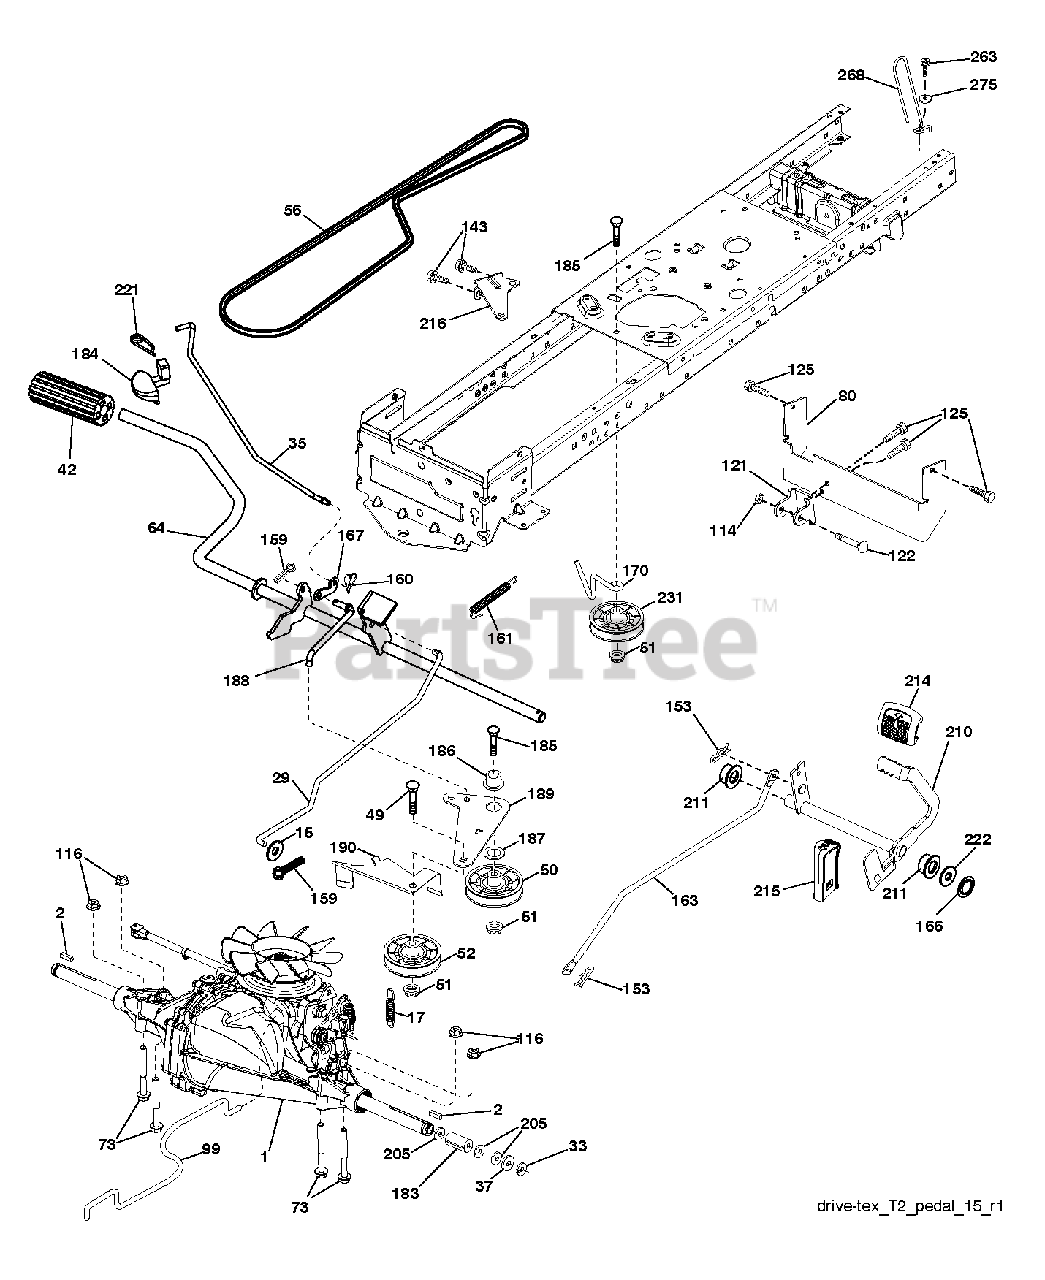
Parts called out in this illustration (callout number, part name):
2	SQUARE KEY
17	SPRING.BRAKE.HG3000/3500
29	ROD BRAKE
33	E-RING LT
35	ROD, BRAKE, PARK
42	PEDAL COVER T
49	BOLT
50	IDLER.FLAT.910.OFFSET
51	NUT LOCK FLG 3/8-16 UNC
52	IDLER.V-GROOVE.910.OFFSET
64	SHAFT.ASM.PEDAL.BRK.CNTR
73	BOLT HEX 5/16-18 GR 5
80	Strap.Torque.T2
99	ROD.ASM.BYPASS.SPRING.T2.FS
114	NUT.71038.31-18.HEX.NYLOCK
116	NUT LOCK HEX FLANGE 5/16-18
121	BRACKET STRAP TORQUE
122	BOLT.5/16-18X2.5
125	SCREW
153	RETAINER M
159	COTTER PIN
160	RETAINER CLIP
161	SPRING, RETURN LT
163	ROD.CONTROL.PCH.T2.TEX
166	NUT.PUSH.625
167	LATCH.BRAKE.SPRING
170	KEEPER.CENTER SPAN.1.688
183	SPACER, AXLE PVST
184	Parking Brake Handle
186	SPACER.RETAINER
187	WASHER 12/32X2X10GA
188	LINK.CLUTCH.GROUND.DRIVE
189	BELLCRANK.GROUND.DRIVE.TEX.
190	KEEPER.BELLCRANK.DRIVE
210	ROCKER.ASM.PEDAL.CONTR
211	BEARING.NYLON
214	PAD PEDAL FORWARD
216	BRACKET.PULLEY.IDLER.W/TEX
221	RETAINER.SPRING.CLIP.H
222	WASHER 21/32 X 1-1/4 X 10 GA.
231	IDLER.V-GROOVE.1.688.OFFSET
263	SCREW, 3/8-16X3/4
275	WASHER
